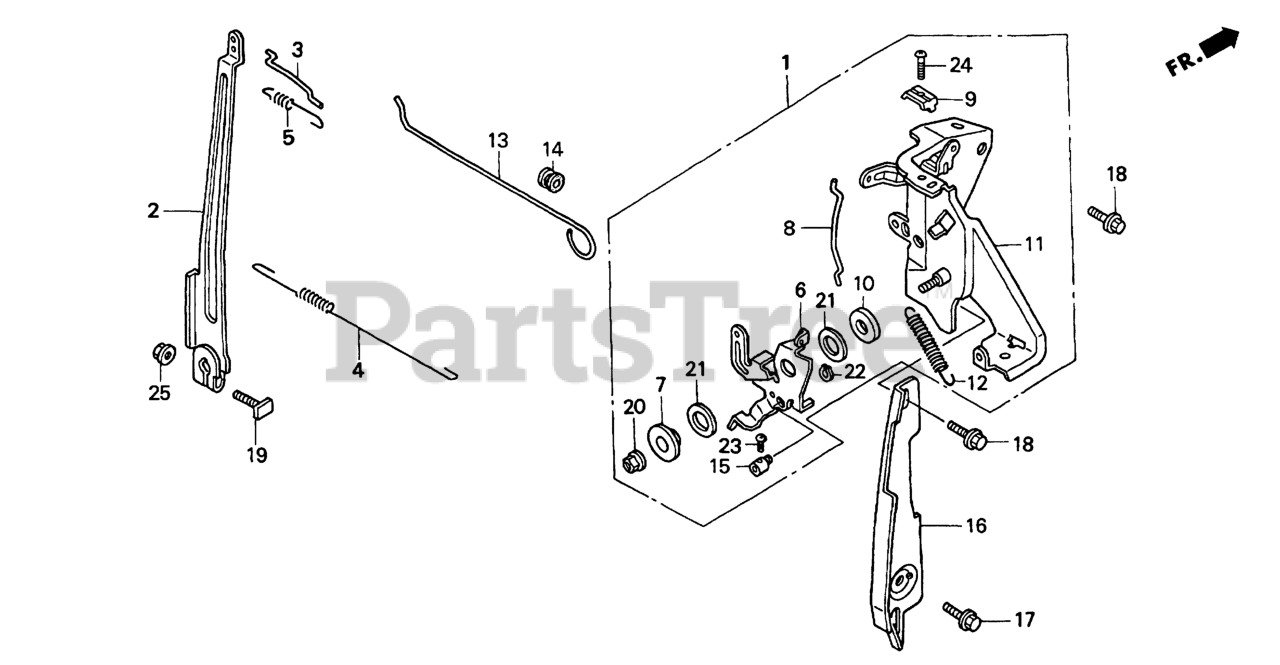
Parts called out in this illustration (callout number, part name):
1	CONTROL ASSY.
2	ARM, GOVERNOR
3	ROD, GOVERNOR
4	SPRING, GOVERNOR
5	SPRING, THROTTLE RETURN
6	LEVER, CONTROL
7	WASHER, CONTROL LEVER
8	ROD, CONTROL LEVER
9	HOLDER, CABLE
10	SPACER, CONTROL LEVER
11	BASE, CONTROL
12	SPRING, CONTROL LEVER RETURN
13	ROD, CHOKE CONTROL
14	GROMMET, CHOKE ROD
15	HOLDER, WIRE
16	PLATE, SIDE
17	BOLT, FLANGE (6X12) (CT200)
18	BOLT, FLANGE (6X14)
19	BOLT, GOVERNOR ARM
20	NUT, SELF-LOCK (6MM)
21	WASHER (12.5MM)
22	CIRCLIP (5MM) Use from Engine SN 2327377.
23	SCREW, PAN (4X6)
24	SCREW, PAN (5X16)
25	NUT, FLANGE (6MM)
